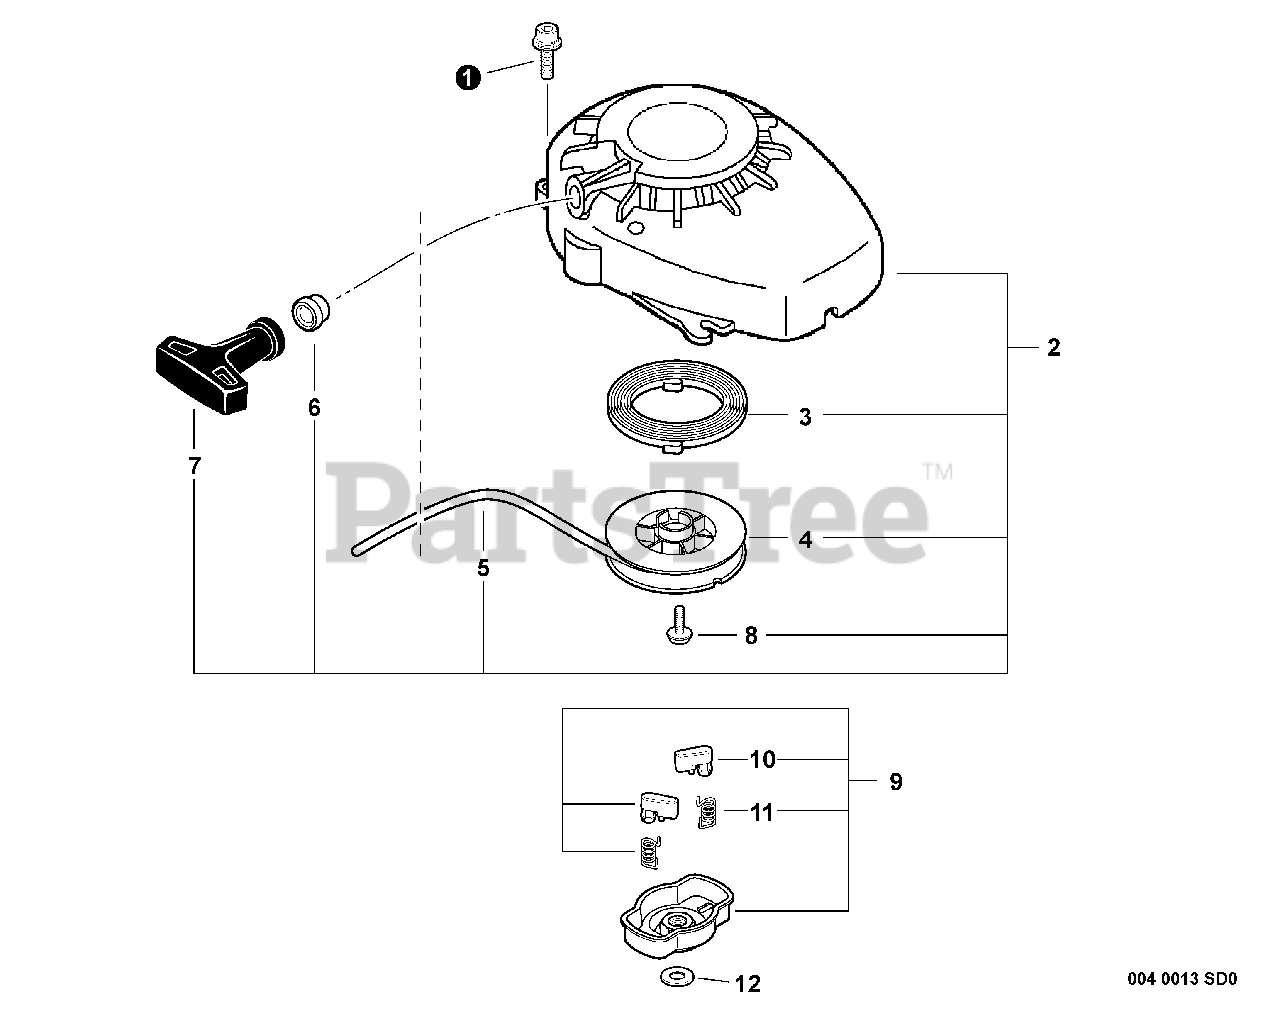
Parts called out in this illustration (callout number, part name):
1	SCREW - 4X16
2	STARTER ASSY - RED
3	SPRING, REWIND
4	REEL, ROPE
5	ROPE, STARTER - 3X1000
6	GUIDE, ROPE
7	GRIP, STARTER
9	STARTER PAWL ASSY
10	PAWL, STARTER - BLACK
11	SPRING, RETURN
12	LOCKWASHER - 8
